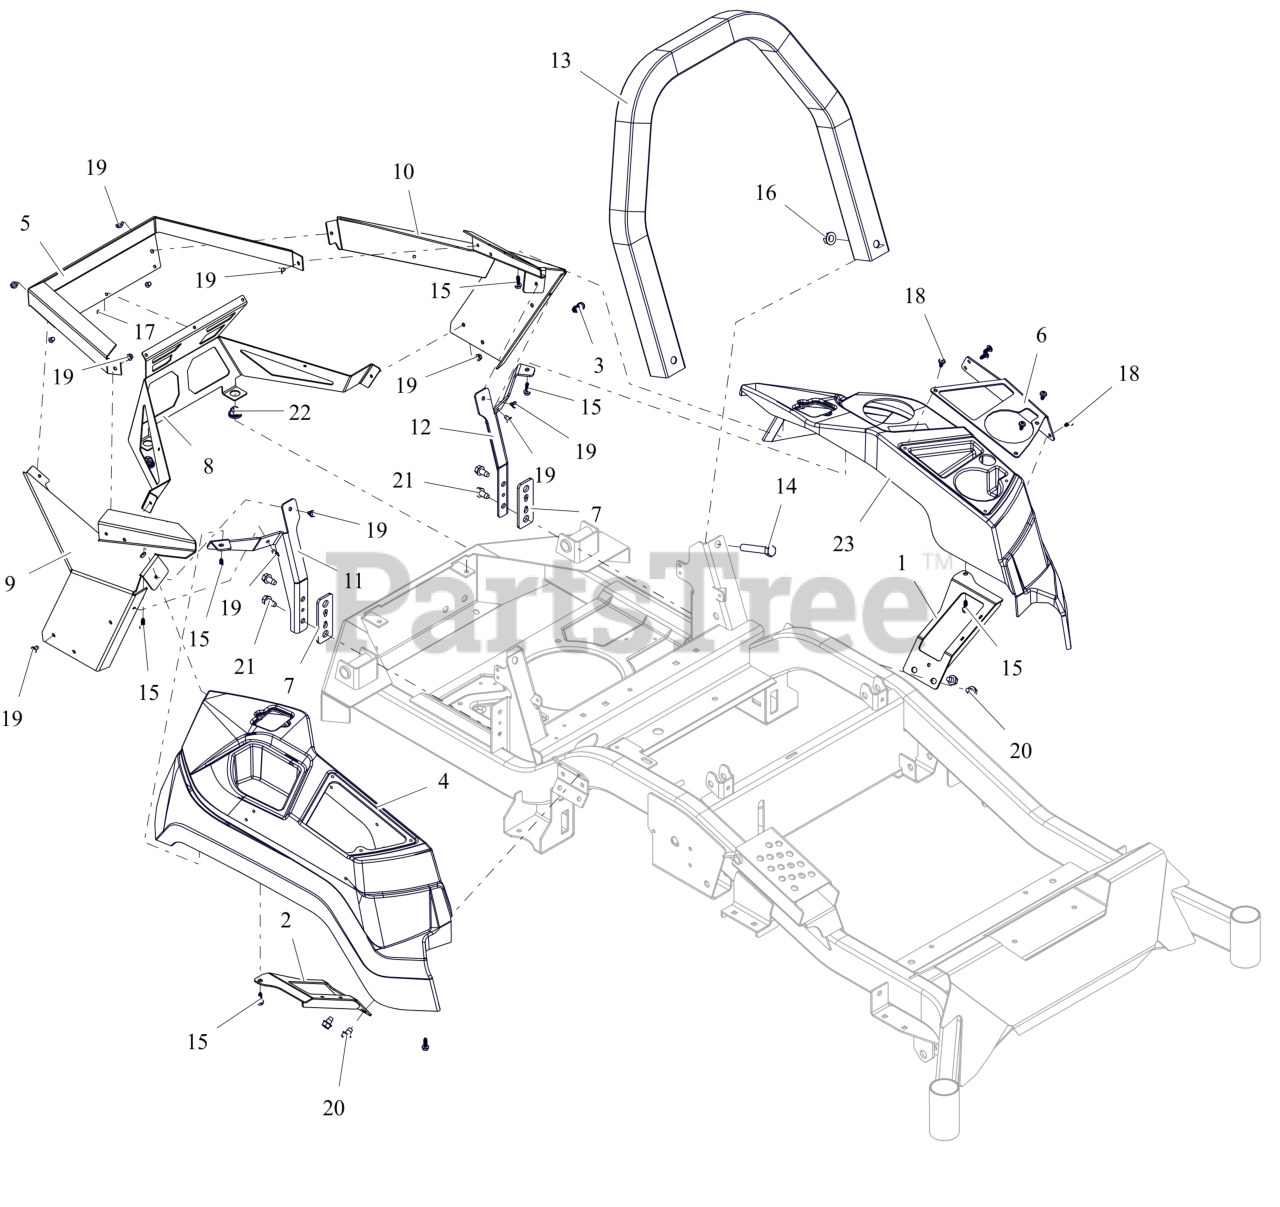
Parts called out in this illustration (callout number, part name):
1	WLDMT, LH FENDER MOUNT
2	WLDMT, RH FENDER MOUNT
3	CLIP, CABLE GUIDE
4	FENDER, RH APEX - 2017
5	GUARD,ENGINE WRAP
6	PLATE, APEX CUP HOLDER COVER
7	PLATE, CONTROL PANEL SPACER
8	GUARD, ENGINE
9	PANEL, RH REAR FENDER MOUNT
10	PANEL, LH REAR FENDER MOUNT
11	BRKT, RH FENDER MTG (ORANGE)
12	BRKT, LH FENDER MOUNT (ORANGE)
13	GUARD, ENGINE -TOP (ORANGE)
14	BLT, HEX .50-13X3.00 G5 ZCC
15	SCR, PLASTITE .25-10X.75 ZCC
16	NUT-LK-CTR-FLG .500-13 GG ZCC
17	RIVET, .1875 AL/AL .126-.250
18	SCR-PAN .25-15X.50 6L H/LZB500
19	SCR,TAP .25-20X.375 HWH TR ZCC
20	SCR,TAP .375-16X.50 HWH TR ZCC
21	SCR,TAP .375-16X.75 HWH TR ZCC
22	GROMMET, 10MM BOLLHOFF
23	FENDER, LH APEX
